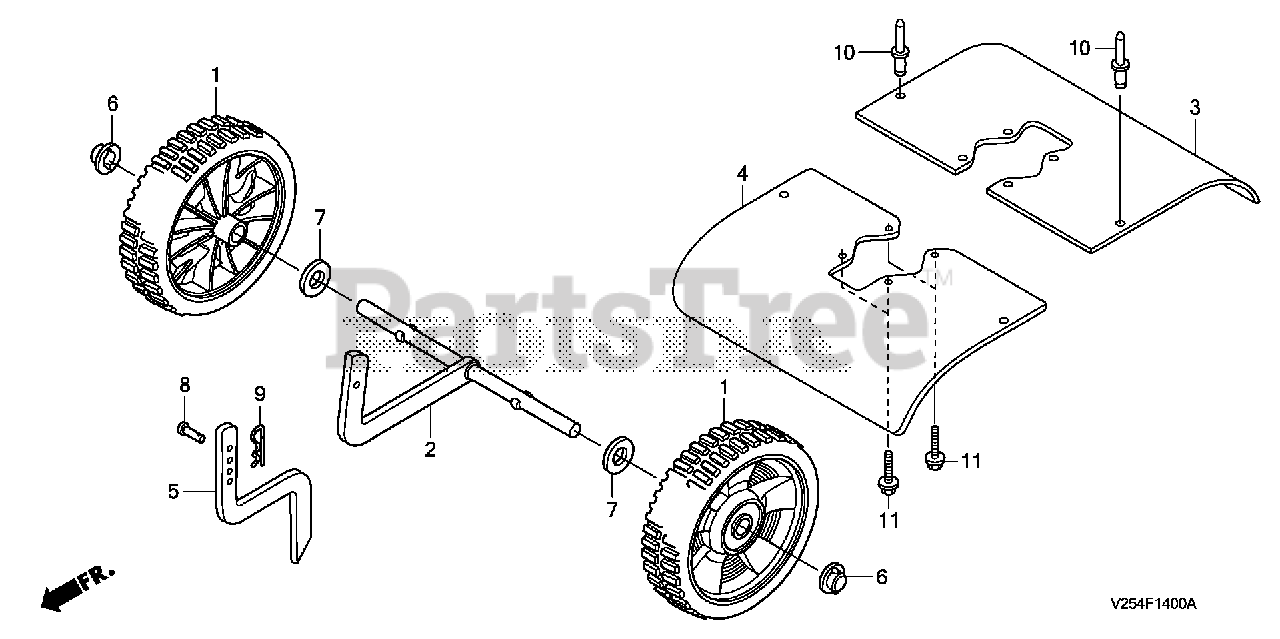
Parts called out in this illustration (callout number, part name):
1	WHEEL, RR.
2	BAR, WHEEL
3	FENDER, RR.
4	FENDER, FR.
6	NUT, PUSH (12.7MM)
7	WASHER, THRUST (13X27X1)
9	PIN, LOCK (6.35MM)
10	RIVET (4.8X9.8)
11	BOLT, FLANGE (6X45)
